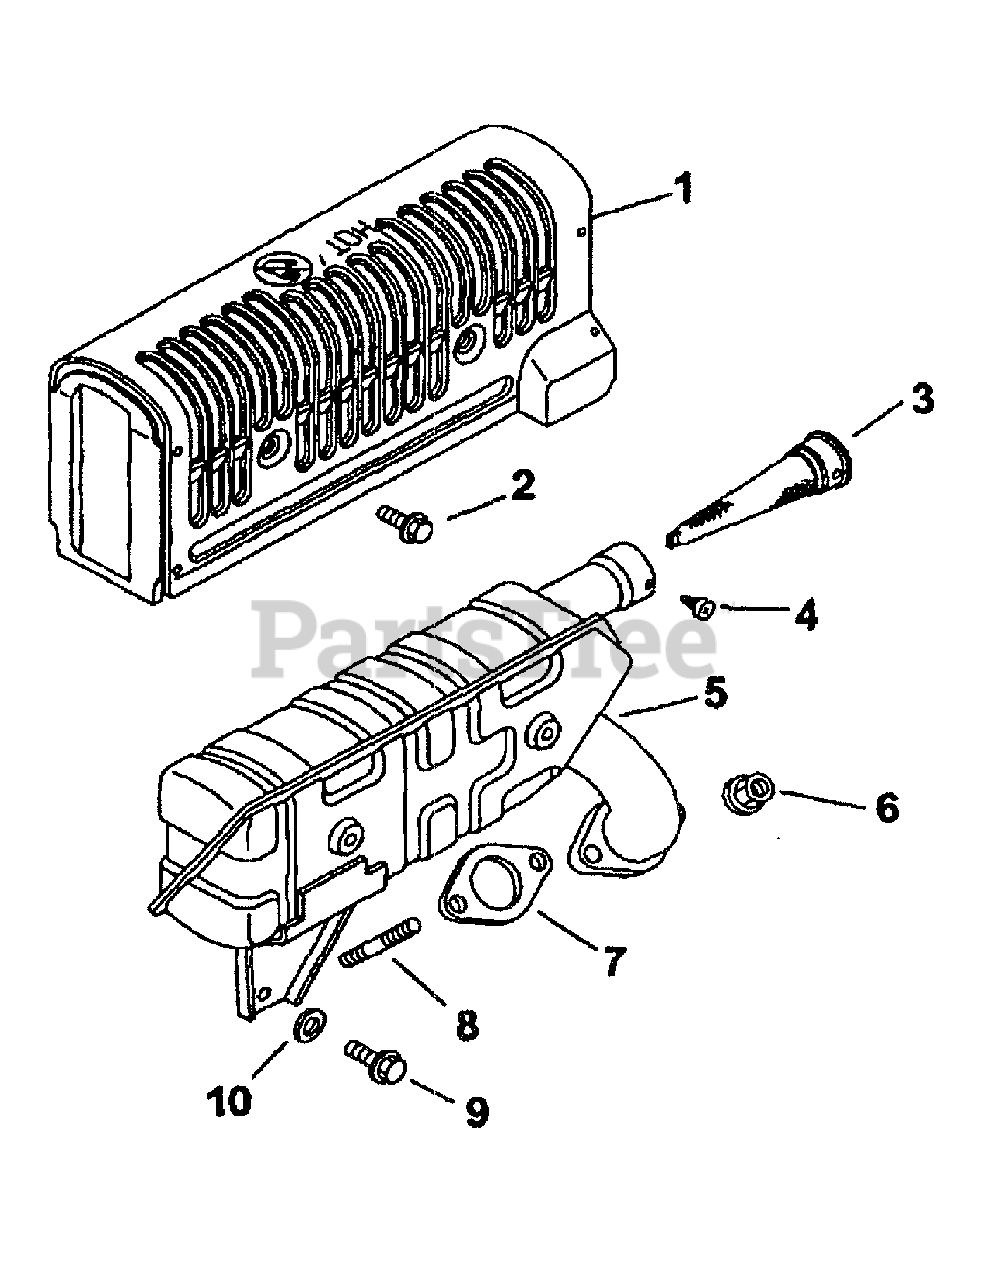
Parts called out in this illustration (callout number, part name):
1	Guard, Kit Muffler
3	Arrestor, Spark
7	Gasket, Exhaust
8	Stud, Exhaust
